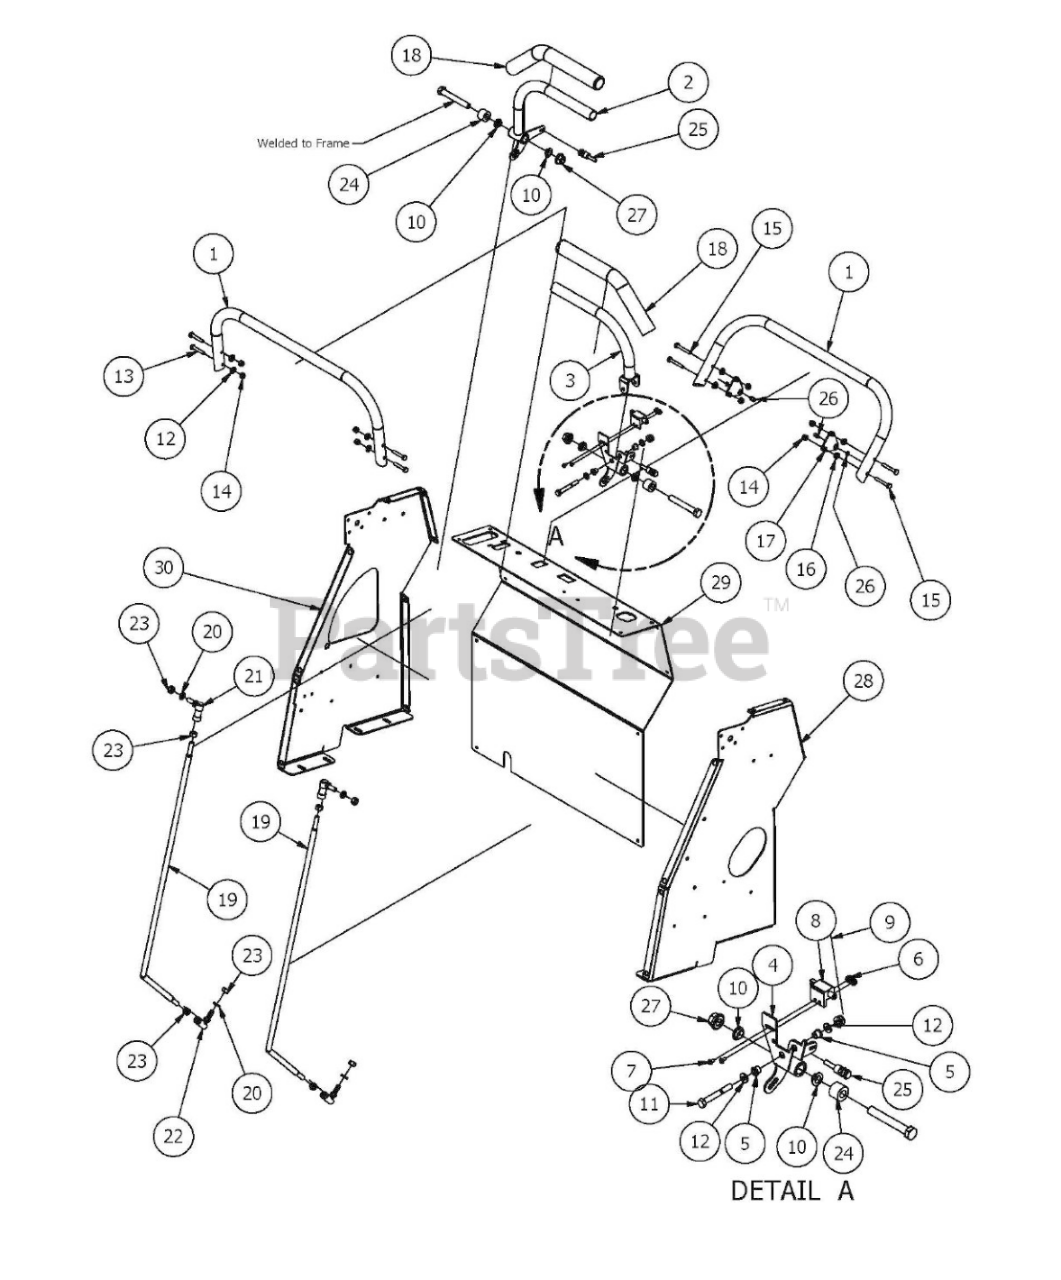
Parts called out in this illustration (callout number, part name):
1	Support Handle Stand Up (Front & Back)
2	2017 Left Steering Handle Assembly
3	Right Steering Handle Assembly
4	2017 Safety Kill Switch Assembly Bracket
5	Stand On Flange Bushing-Steering Arms
6	#10 Nylock Nut
7	1024 X 5/8" Buttonhead Bolt
8	Safety Switch
9	5/16-18 Nylon Flange Nut
10	Bushing for 2012 Drive Arms
11	5/16" x 2 1/2" Bolt
12	1/4" Flat Washer
13	1/4-20 x 1 1/2" Bolt
14	1/4" Nylock Nut
15	1/4-20x 1-3/4" Hex Bolt
16	1/4-20 Hex Flange Nuts Zinc w/Serrations
17	2017 Neutral Safety Tab
18	Black Steering Grip
19	Push Rod Stand On
20	3/8" Lock Washer
21	3/8-24 Quick Release Ball Joint
22	3/8-24 Ball Joint
23	3/8" F Threaded Nut
24	Steering Arm Spacer-Stand On
25	Safety Switch Harness
26	Magnet-Steering Arm-Stand On
27	1/2-13 Hex Flange (GR.G) ZC
28	2015 Podium Panel Right
29	2015 Podium Front Panel
30	2015 Podium Panel Left
